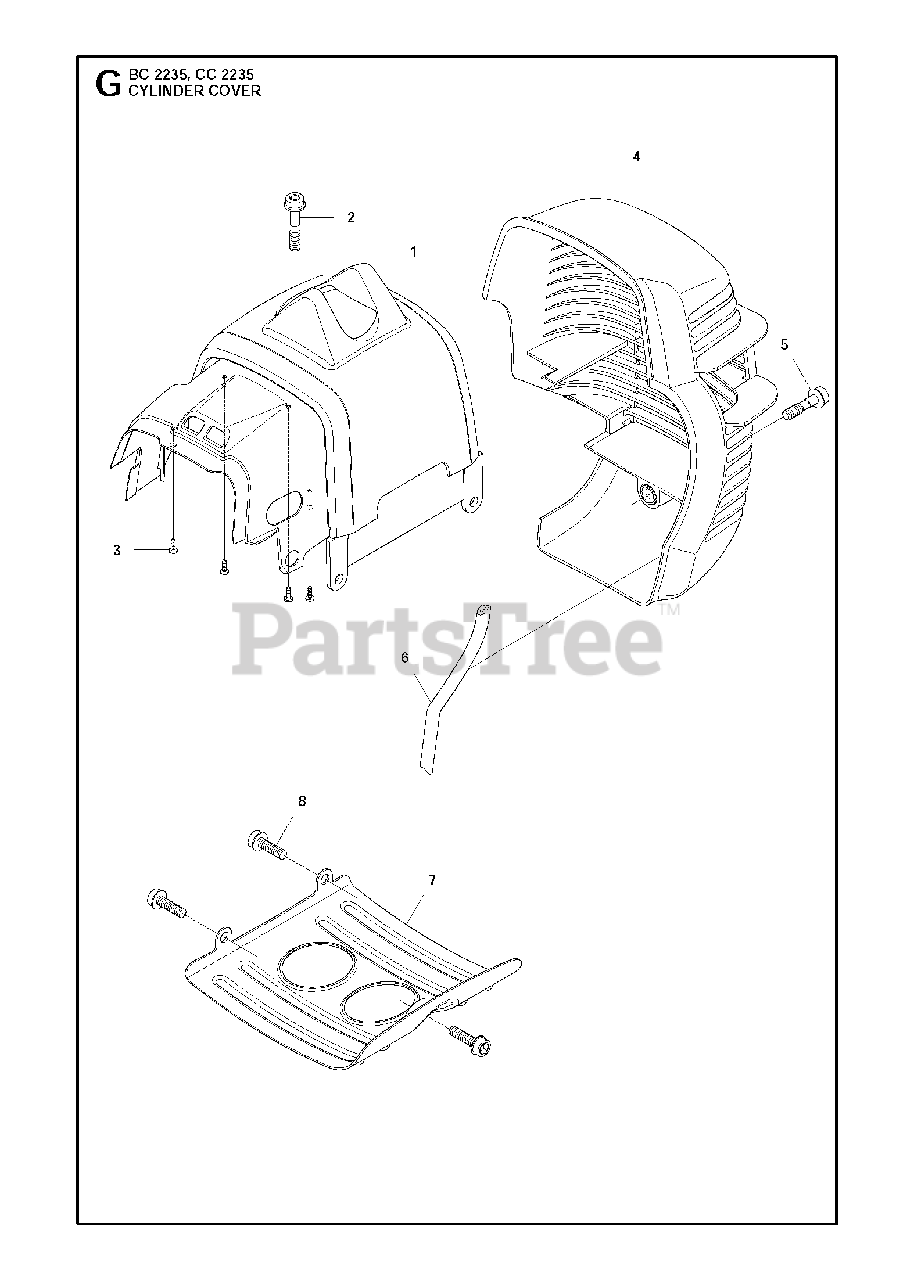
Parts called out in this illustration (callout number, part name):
1	CYLINDER COVER
2	SCREW IHSCFMO
4	HEAT PROTECTOR
5	HEAT PROTECTOR
